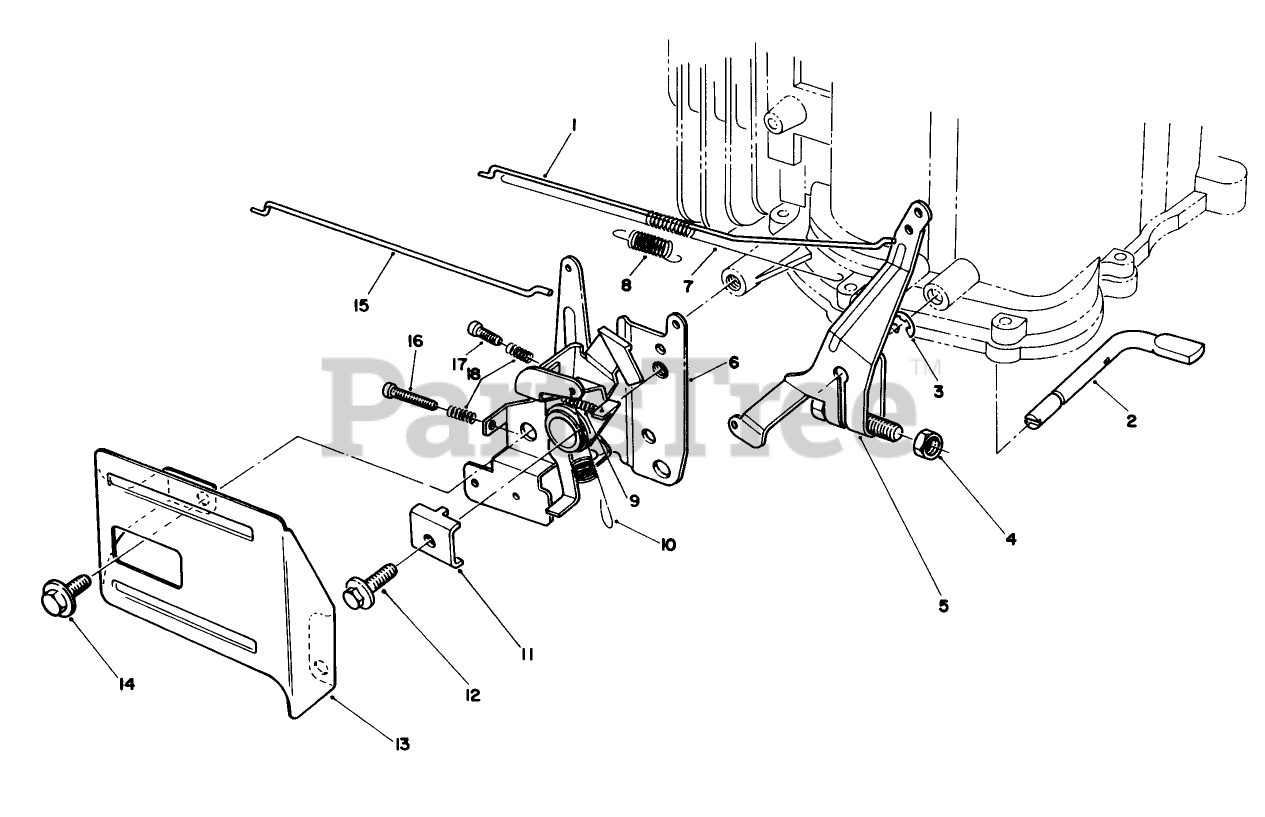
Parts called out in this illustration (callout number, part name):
7	SPRING
8	SPRING
10	SPRING
11	CLAMP-CABLE
13	THROTTLE GUARD *
18	SPRING
